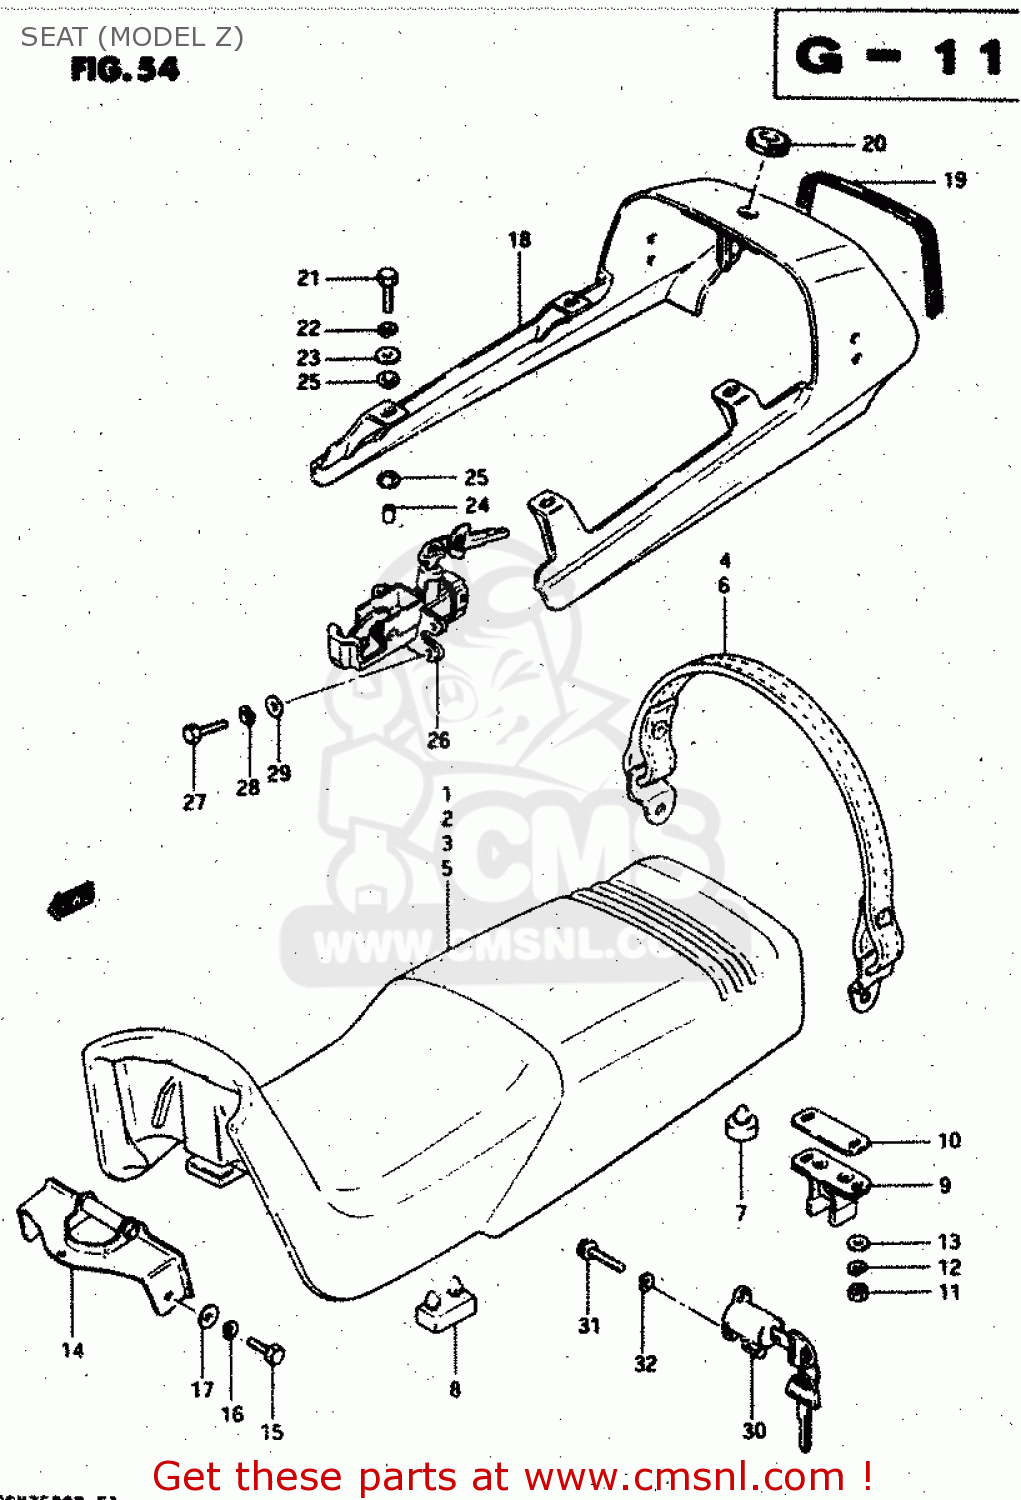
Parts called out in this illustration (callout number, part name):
1	SEAT ASSY (BLUE)
2	SEAT ASSY (BLACK)
3	SEAT ASSY (BLUE)
4	BAND, SEAT GRIP (BLUE)
5	SEAT ASSY (BLACK)
6	BAND, SEAT GRIP (BLACK)
7	CUSHION
8	CUSHION
9	STRIKER,SEAT LOCK
10	SHIM,SEAT LOCK STRIKER
11	NUT 6MM
12	LOCK WASHER
13	WASHER
14	PLATE,SEAT HOOK FR
15	BOLT
16	LOCK WASHER
17	WASHER
18	COVER,SEAT TAI
19	MOLD, SEAT TAIL
20	GROMMET,SEAT LOCK HOLE
21	BOLT
22	LOCK WASHER
23	WASHER (6.5X24X1.6)
24	SPACER (7X10X12)
25	CUSHION
26	LOCK SET
27	BOLT
28	LOCK WASHER
29	WASHER
30	LOCK ASSEMBLY,HELMET
31	BOLT
32	LOCK WASHER
